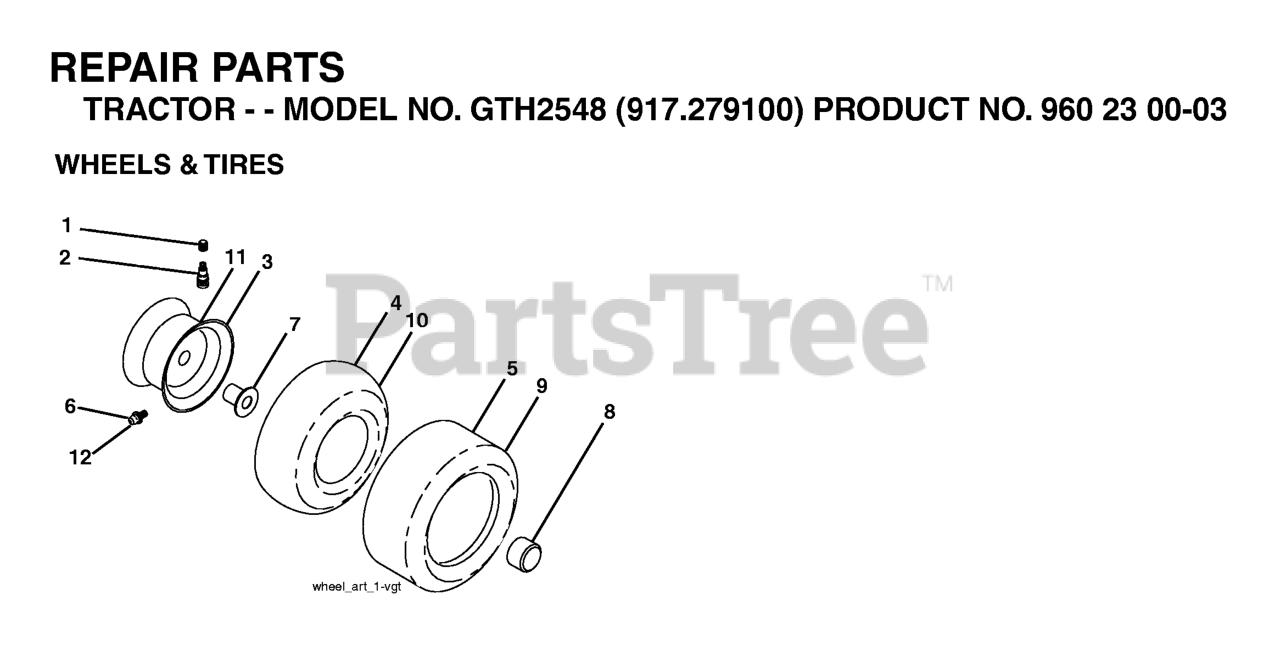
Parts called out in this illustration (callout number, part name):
2	VALVE STEM LT
3	RIM ASSEMBLY, FRONT
4	TUBE.16X6.5/7.5-8
5	TIRE HEAVY DUTY
6	FITTING LT
7	BEARING T
8	CAP, AXLE BLK
9	TIRE HEAVY DUTY
10	TUBE.23X9.5-12
11	RIM.ASM.12X7.REAR.SILVER
12	ZERK FITTING M
